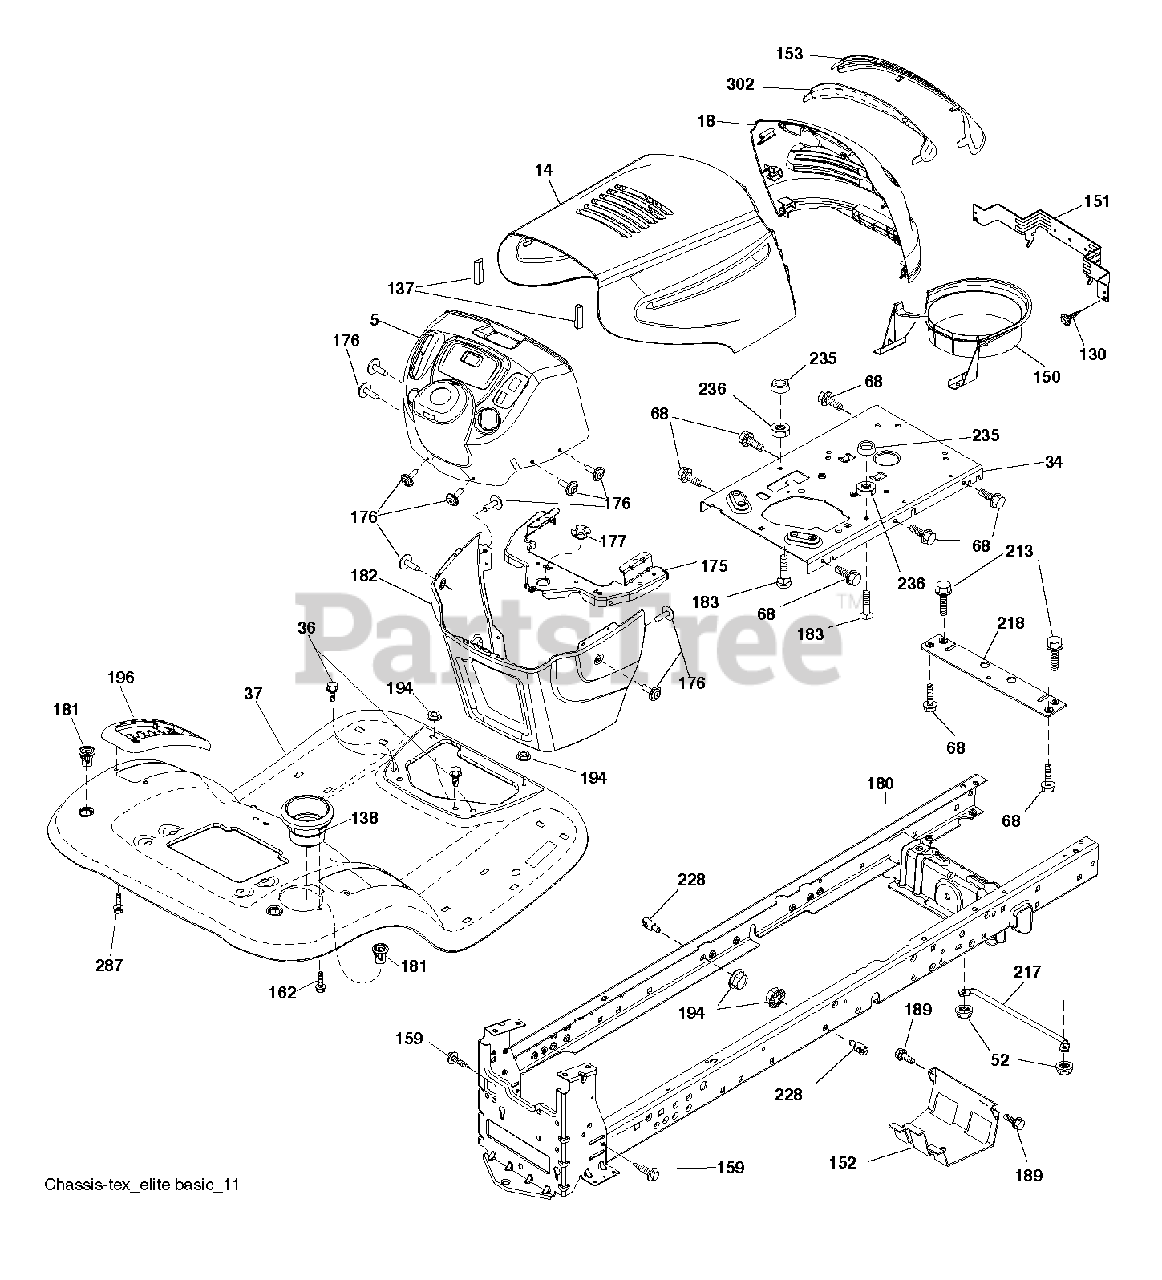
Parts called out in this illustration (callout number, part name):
5	DASH.P/L.TEX.CBL.CL.N/CHK.BLAC
14	HOOD.STEEL.ELITE.YELLOW
18	GRILLE.ELITE.BASIC.LT.BLACK
34	PLATE.ENGINE.WELDED.CHASSIS
36	SCREW 5/16"
52	LOCKNUT
68	SCREW LT
130	SCREW.#10 X 0.750.BOS (2 2)
137	BUMPER.HOOD.LARGE.1.75"
138	CUPHOLDER.TL.TEX.BLACK
150	DUCT.INTAKE.AIR.KAW
151	BRACKET PIVOT
152	SHIELD.BROWNING.W/TEX
153	LENS.GRILLE.BASIC.BAR.LT.CLR
159	SCREW, 3/8-16X3/4
162	SCREW.HI-LO.CONSOLE
175	CROSSMEMBER.LT
176	SCREW.#10-24X5/8.RN.QU
177	BUSHING STEERING
180	CHASSIS
181	FEND/FTRST.PCH.CPH.NFW
182	DASH.LOWER.LT.CCS
183	BOLT.5/16-18X1-1/4 FULL THD
189	SCREW
194	NUT LOCK HEX FLANGE 5/16-18
196	CONSOLE.ASM.DECKLFT.BL/RBT.TLT
213	BOLT
217	ROD.PIVOT.HOOD
218	X-PIECE.HOOD.STOP.NON/
228	STUD.FASTNER.W/ANTI-ROTATE
235	SPACER FENDER
236	NUT.CENTERLOCK.5/16-
287	SCREW 1/4X20
302	INSERT.LENS.REFLECTIVE.LEFT
